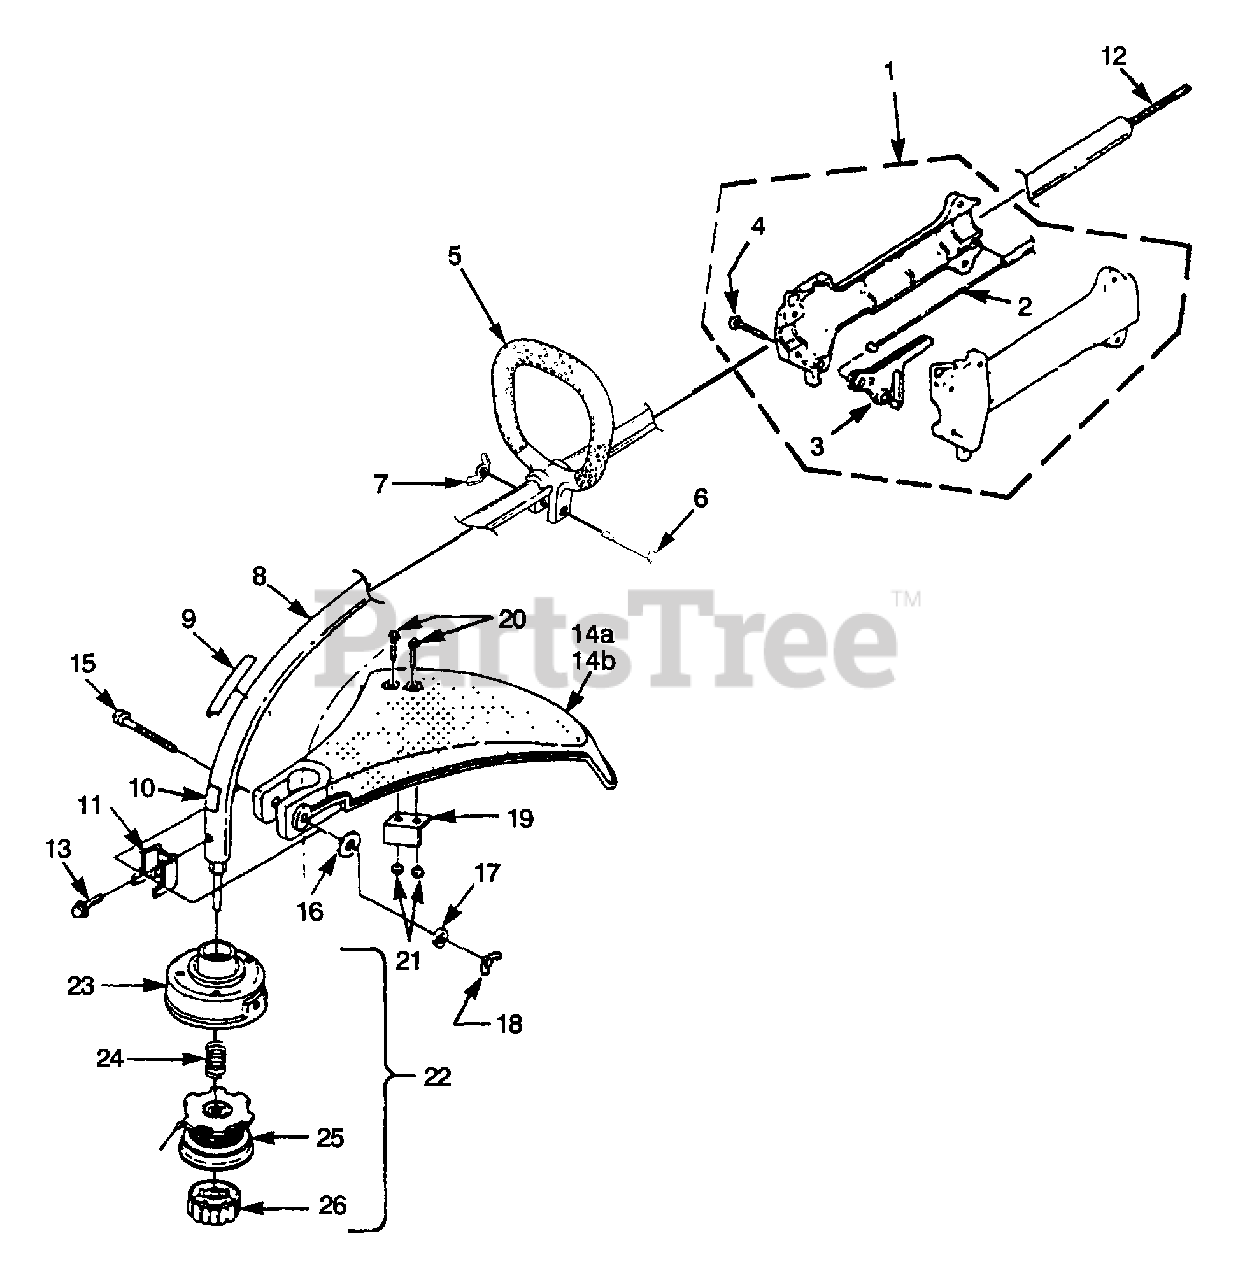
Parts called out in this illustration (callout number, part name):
1	HANDLE GRIP ASSEMBLY
2	CABLE - Throttle
3	TRIGGER
4	SCREW - Thread Forming (#8 X 3/4")
5	FRONT HANDLE KIT
6	SCREW - Cap Hex Hd (10-24 X 2")
7	NUT - Wing (10-24)
8	HOUSING - Drive Shaft
9	DECAL - Starting Instructions
10	DECAL - Warning
11	CLAMP
12	SHAFT - Flexible
13	SCREW - Sems Hex Hd (#10 X 1/2)
14A	DEFLECTOR & BLADE KIT (55 Deg.)
14B	DEFLECTOR & BLADE KIT (100 Deg.)
15	SCREW - Cap Hex Hd (10-24 X 2")
16	WASHER - Flat (1/4")
17	WASHER - Lock (1/4")
18	NUT - Wing (10-24)
19	BLADE - Cut-Off
20	SCREW - Mech Hex Hd (10-24 X 7/8")
21	NUT - Hex (10-24)
22	STRINGHEAD - Complete (.080" Line)
23	HOUSING & EYELET
24	SPRING - Compression
25	SPOOL & STRING (.080" Line)
26	RETAINER - Spool
